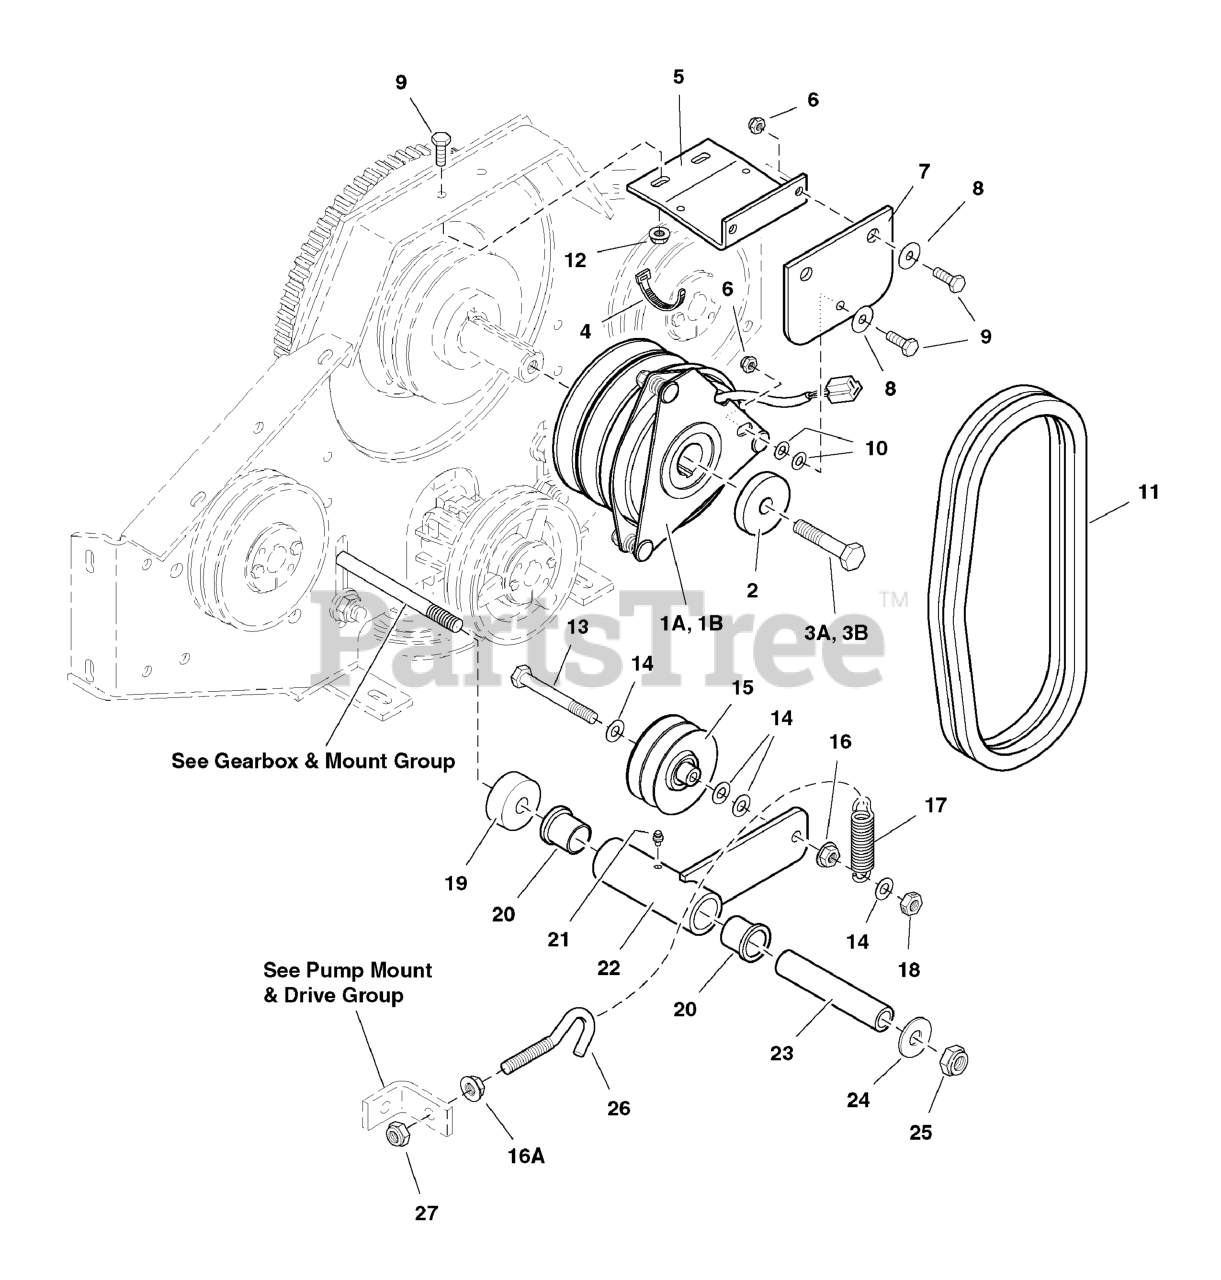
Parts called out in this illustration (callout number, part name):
1A	KIT, CLUTCH & BOLT
1B	ELECTRIC CLUTCH
2	SPACER, .45 x 1.88 x .38
3A	CRANKSHAFT BOLT, 7/16 x 3
3B	CRANKSHAFT BOLT, 7/16 x 3-1/2
4	TIE WRAP
5	CLUTCH ANCHOR
6	NUT, 5/16-24 HEX NYLON LOCK
7	CLUTCH ANCHOR PAD
8	WASHER, 5/16" Fender
9	BOLT, 5/16-18 X 1 GD5 YZ
10	WASHER, 5/16" SAE
11	BELT, Clutch Drive (set of 2)
12	NUT, 5/16-18 HEX SERRATED FLANGE (SMALL)
13	BOLT, 3/8-16 X 3" GD5 CZ
14	WASHER, 3/8 SAE
15	PULLEY, Idler
16	NUT, 3/8-16 Hex Serrated Flange
16A	NUT, 3/8-16 Hex Serrated Flange
17	SPRING, Extension
18	NUT, 3/8-16 Hex Side Lock
19	SPACER, Clutch Idler
20	BUSHING, Flange
21	GREASE FITTING
22	CLUTCH DRIVE IDLER ARM
23	PIVOT SLEEVE, Long
24	WASHER, 1/2 SAE
25	NUT, 1/2-13 HEX NYLON LOCK
26	SCREW HOOK, 3/8-16 x 4-1/4
27	NUT, 3/8-16 HEX NYLON LOCK
